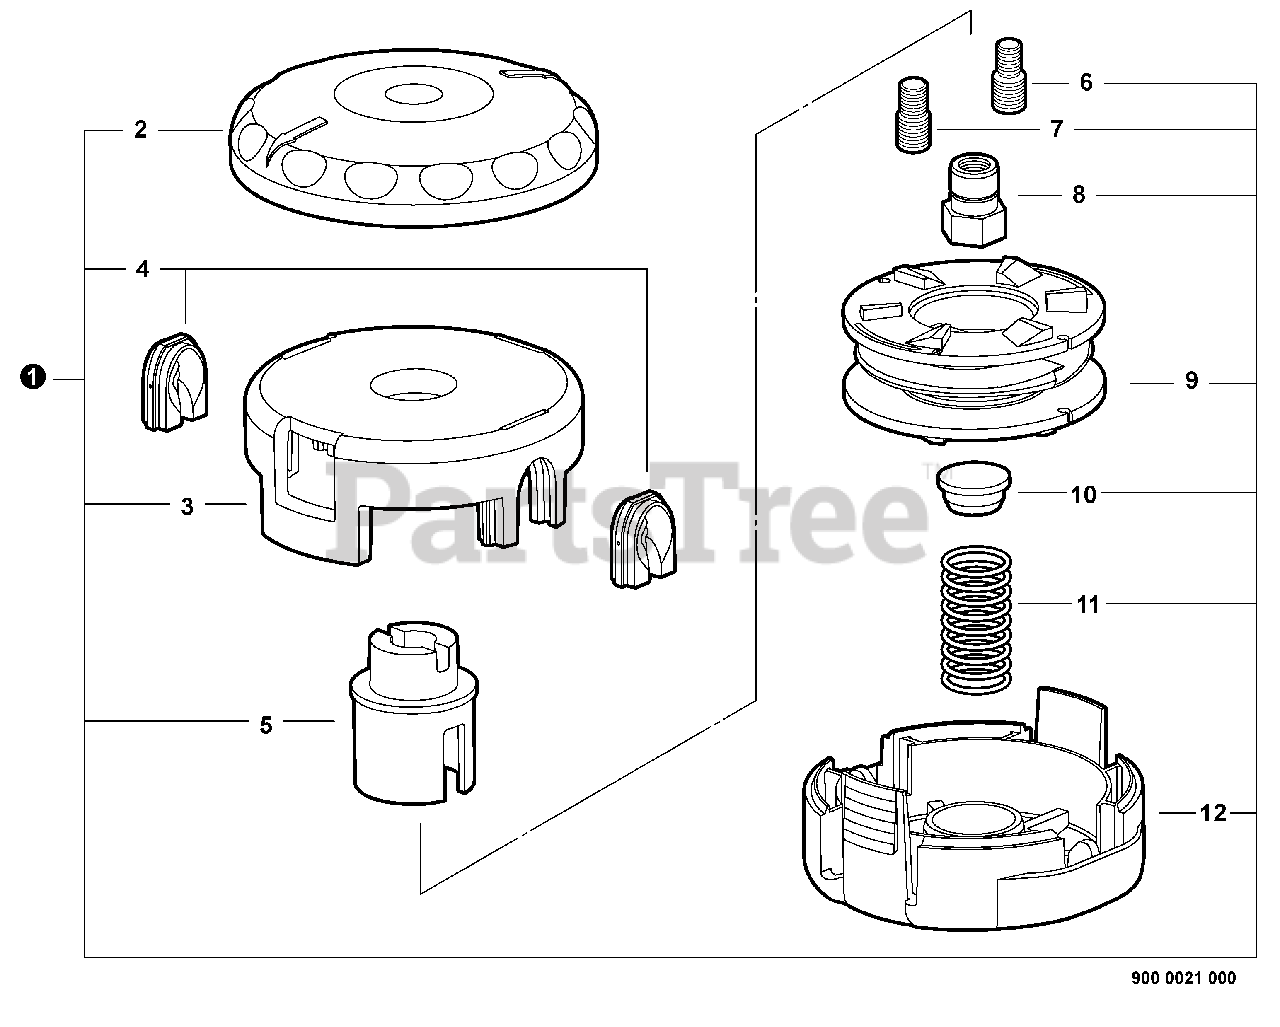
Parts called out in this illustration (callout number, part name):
1	SPEED-FEED 375 TRIMMER HEAD
3	COVER, SPOOL
6	STUD - GOLD -- LEFT HAND
7	STUD - 8 -- SILVER
8	ARBOR
10	CAP
11	SPRING
